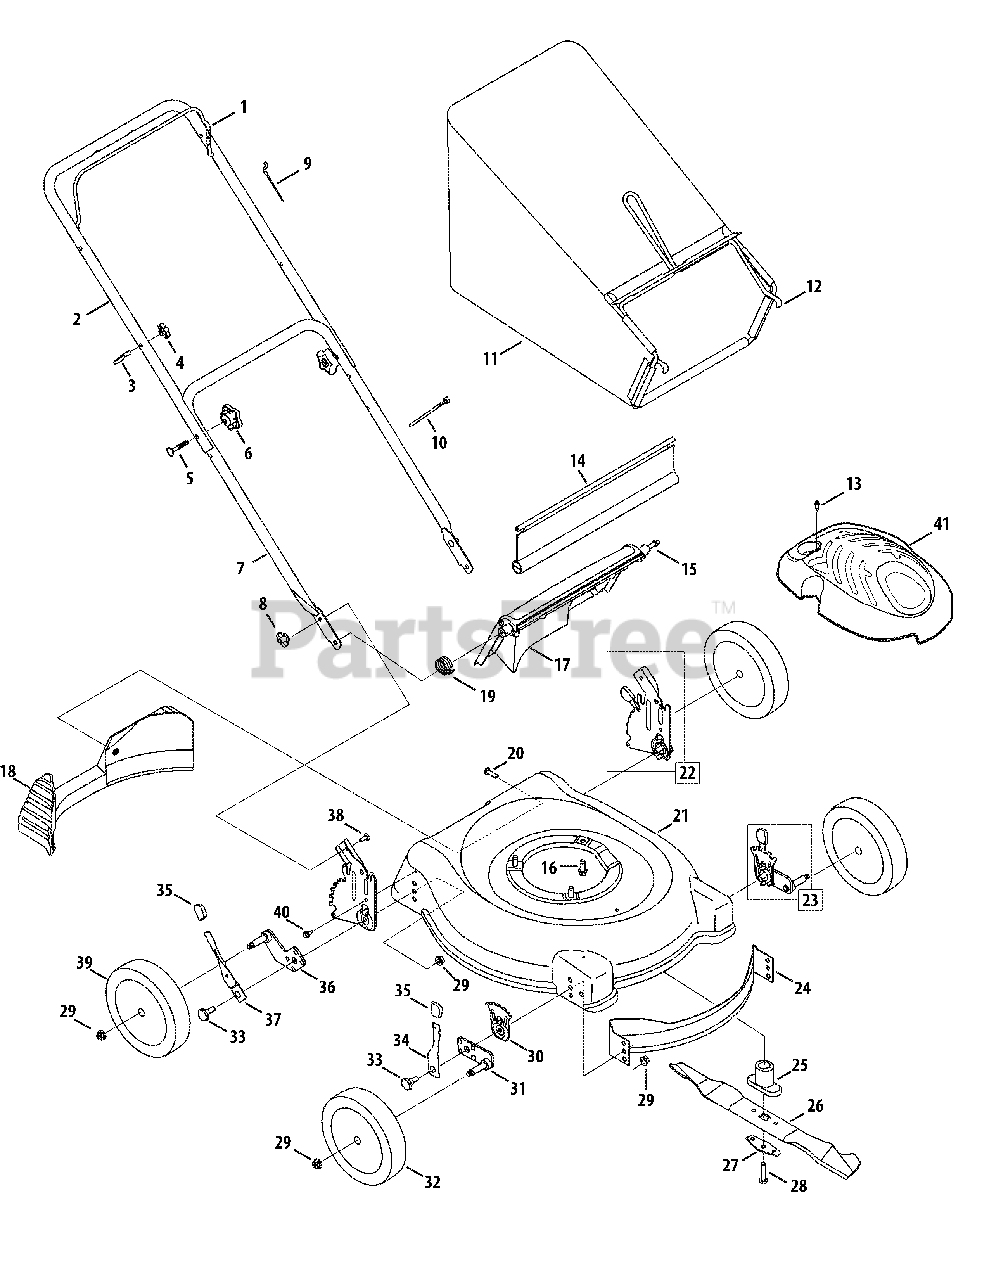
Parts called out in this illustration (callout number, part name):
1	Blade Control
2	Upper Handle
3	Rope Guide
4	Wing Nut, 1/4-20
5	Carriage Bolt, 5/16-18 x 2
6	Hand Star Knob
7	Lower Handle
8	Wing Nut, 1/4-20
9	Control Cable
10	Cable Tie
11	Grass Bag
12	Grass Bag Frame
13	Screw, HL, #12-16 x 1.00
14	Trail Shield
15	Rear Door Pivot Rod
16	TT Screw, 3/8-16 x 1
17	Rear Discharge Door
18	Rear Baffle
19	Torsion Spring RH
20	Screw, 1/4-15 x 1.00
21	Deck 21 inch
22	Handle Bracket Assy - RH
22	Handle Bracket Assy - LH
23	Height Adj. Assy. Frt - LH
23	Height Adj. Assy. Frt - RH
24	Front Baffle
25	Blade Adapter, #6 x 2.15 w/Star
26	Mulch Blade
27	Blade Bell Support
28	Screw, 3/8-24 x 2.50
29	Flange Lock Nut, 3/8-16
30	Height Adjustment Plate
31	Pivot Arm Assy - RH
31	Pivot Arm Assy - LH
32	Front Wheel, 7 x 1.8
33	Screw, Shldr., .500 Dia. X .385
34	Spring Lever
35	Height Adjustment Knob
36	Pivot Arm Assembly - RH
36	Pivot Arm Assembly - LH
37	Spring Lever
38	Carriage Bolt, 1/4-20
39	Rear Wheel, 8 x 1.8
40	Screw, 1/4-20 x .625
41	Engine Shroud
